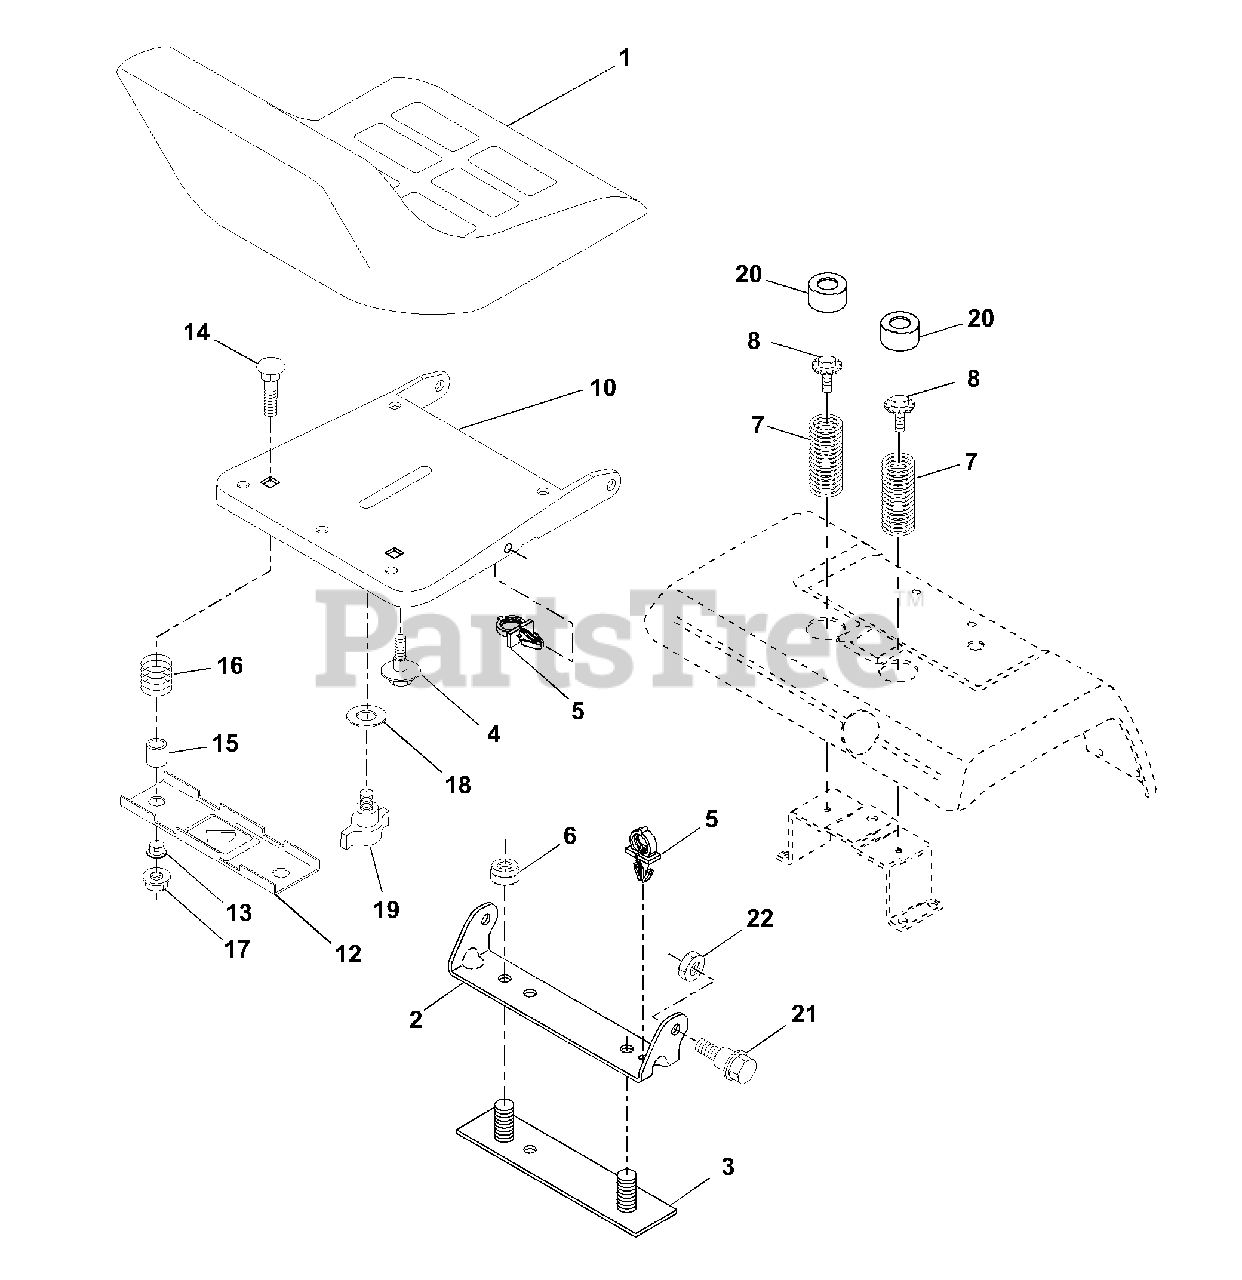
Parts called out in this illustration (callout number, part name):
1	Seat
2	Bracket, Pivot Seat
3	Strap, Fender Asm.
4	Bolt, Shoulder 5/16-18 x .62
5	Clip, Push-In Hinged
6	Nut, Crownlock 3/8-16
7	Spring, Seat Cprsn.
8	Bolt 5/16-18 UNC x 3/4 w/Sems
10	Pan, Seat
12	Bracket, Mounting Switch
13	Bushing, Snap
14	Bolt, Carriage 1/4-20 x 1-1/2
15	Spacer, Split
16	Spring, Cprsn.
17	Nut, Lock 1/4 Lg. Flg. Gr. 5
18	Washer 17/32 x 1-3/16 x 12 Ga.
19	Knob, Seat
20	Cap, Spring Seat Blk
21	Bolt 5/16-18 Unc-2A
22	Nut, Crownlock 5/16-18
